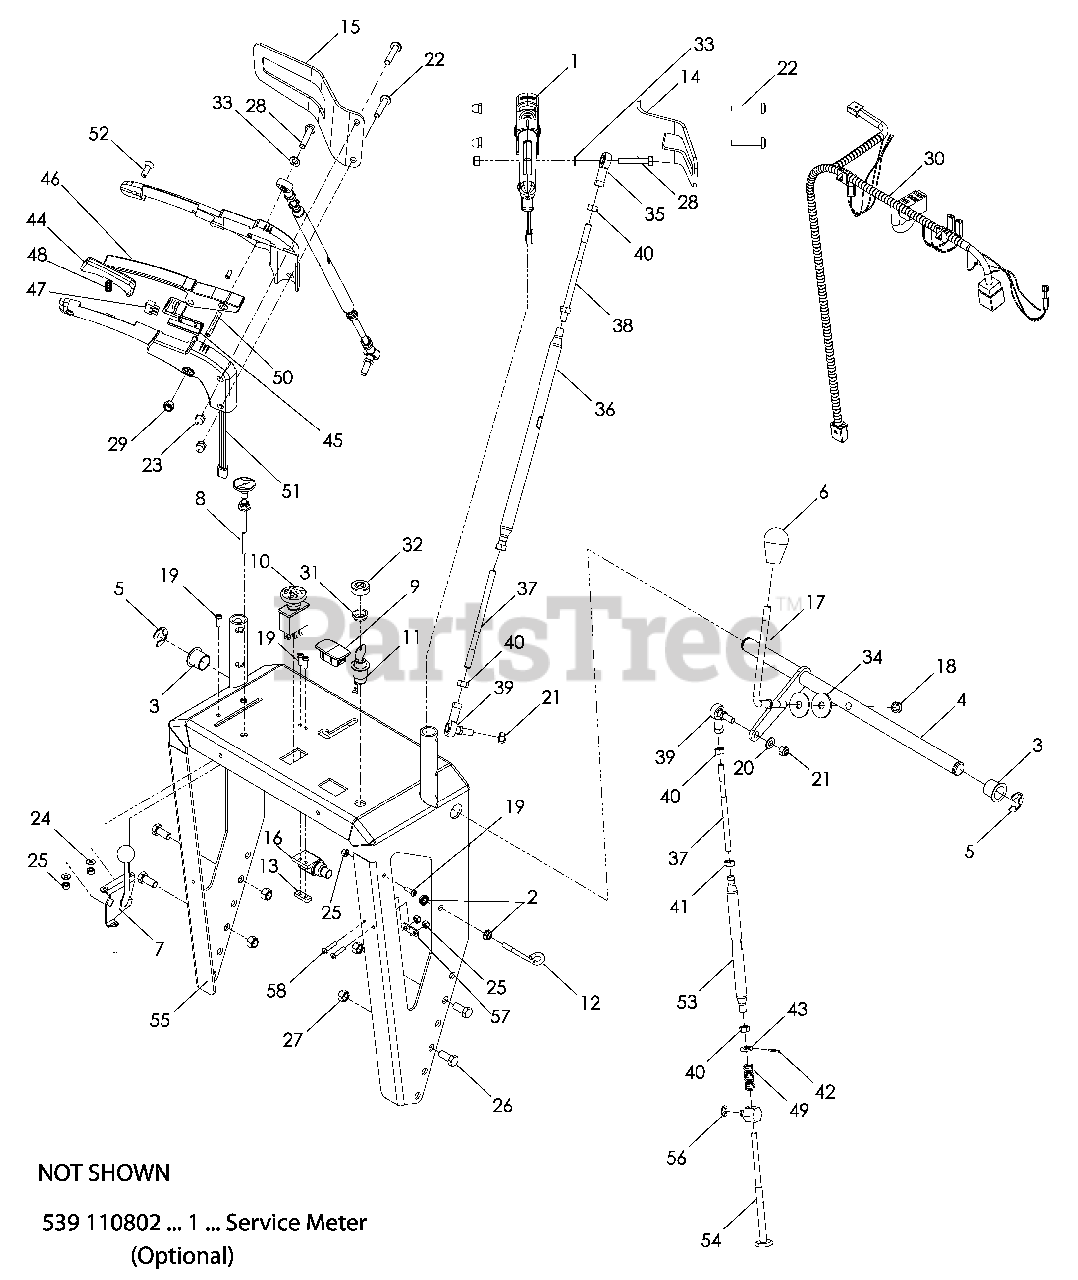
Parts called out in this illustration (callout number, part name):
1	GRIP ASSEM
2	NUT 5/16-18 HEX WHIZLK
3	BEARING, FLANGE
4	SPEED CONTROL
5	E RING, 20MM
6	KNOB, SHIFT
7	THROTTLE CONTROL
8	CONTROL, CHOKE
9	PLUG, DASH, SVC MINDER
10	CLUTCH SWITCH
11	SWITCH, IGNITION
12	GUIDE, ROPE
13	PLATE, NUT
14	GUARD, HAND RH
15	GUARD, HAND LH
16	SWITCH, NC
17	ROD, SHIFT
18	NUT 3/8-16 HEX JAM NYLOC
19	SCREW #10-24 x ½ HEX
20	WASHER 5/16 SAE FLAT
21	NUT M8 x 1.25 NYLOC
22	SCREW, PAN HD 5/16-18 x 1¾
23	NUT, ACORN 5/16-18
24	WASHER #10 FLAT
25	NUT #10-24 HEX NYLOC
26	HCS 3/8-16 x 7/8
27	NUT 3/8-16 HEX NYLOC
28	HCS 5/16-18 x 1¾
29	NUT 5/16-18 HEX NYLOC
30	HARNESS, UPPER HANDLE
31	NUT, IGNITION SWITCH
32	CAP, IGNITION SWITCH NUT
33	WASHER 5/16 SLW
34	WASHER, CONE
35	ROD END 8 MM, RH
36	TUBE, ADJUSTING
39	ROD END 8 MM, W/STUD
40	NUT .8MM x 1.25 HEX
41	NUT .8MM x 1.25 LH
42	ROLL PIN 3 MM
43	WASHER, 10 MM
44	ACTUATOR, OPC
45	LOCK, NEUTRAL
50	PIN, GROOVE ¼ x 1½
51	HARNESS, SWITCH
52	SCREW, OVAL HEAD 6MM
53	TUBE, ADJUSTING
54	ROD, HEADED
55	UPPER HANDLE W/DECAL
56	E-RING, 10MM
57	PLATE, RESISTOR
58	SCREW #10-24 x 7/8 RD HD
